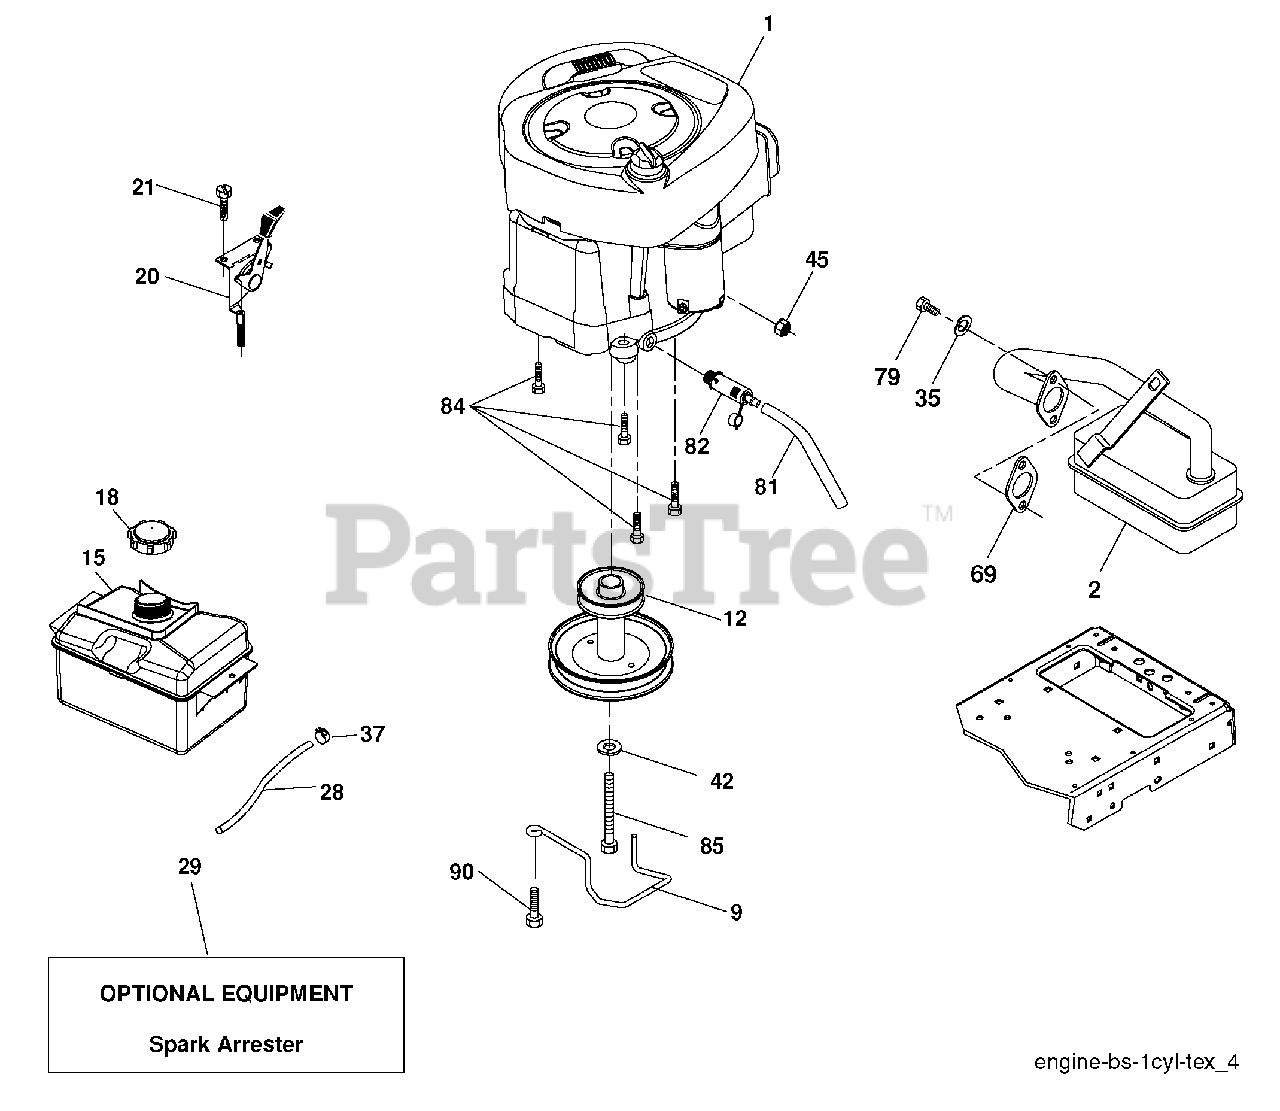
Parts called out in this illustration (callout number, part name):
2	Muffl er
9	Keeper Belt Engine
12	Pulley Engine
15	Tank Fuel
18	Cap Asm
20	Control Throttle
21	Screw 10 x 3/4 Single Lead-Hex
28	Fuel Line
29	Spark Arrester Kit
35	Washer, Split
37	Clamp Hose
42	Washer Lock 7/16
45	Nut Keps Hex 1/4-20 unc
69	Gasket
79	Screw Socket Head 5/16-18 x .75
81	Tube Drain Oil Easy
82	Plug Drain Oil
84	Screw 3/8-16 x 1-1/4
85	Bolt Hex 7/16-20 x 4 x Gr. 5-1.5 Thr.
90	Screw 3/8-16 x 1
